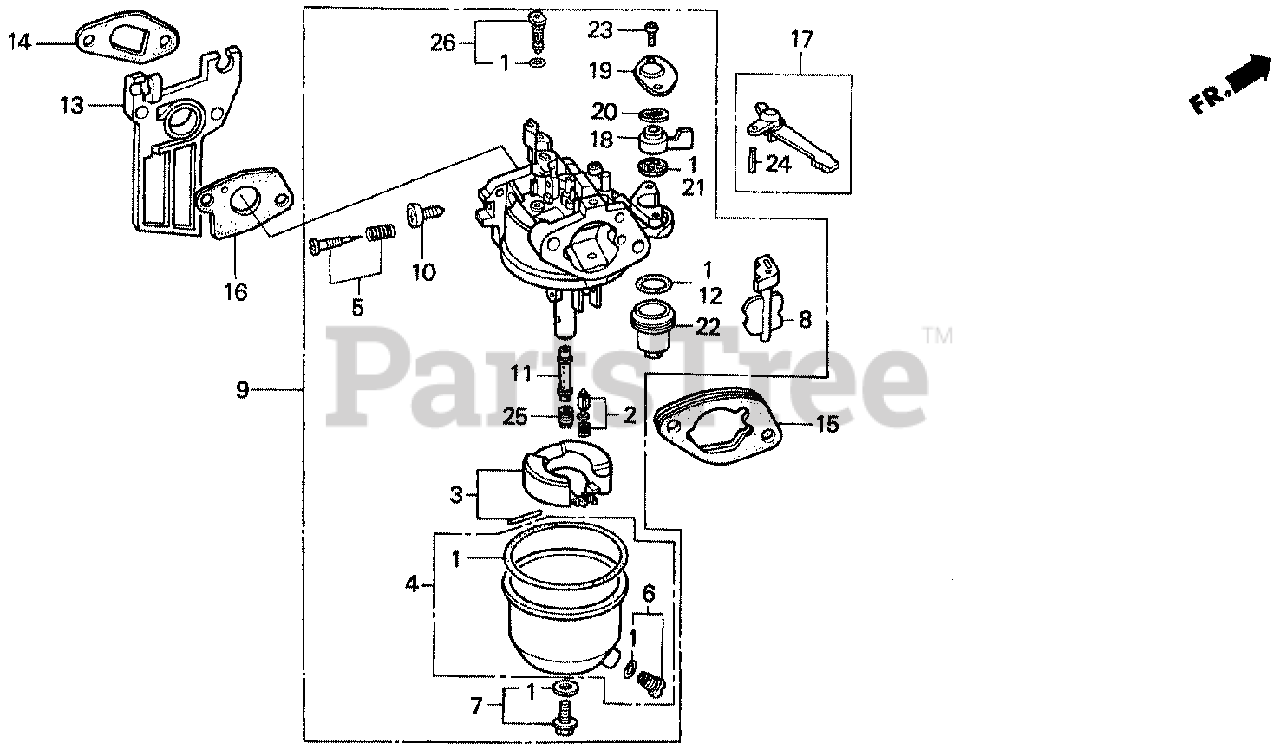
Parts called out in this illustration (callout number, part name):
1	GASKET SET
2	VALVE SET, FLOAT
4	CHAMBER SET, FLOAT
6	SCREW SET, DRAIN
7	SCREW SET B
9	CARBURETOR ASSY. (BE65E B)
10	SCREW, THROTTLE STOP
11	NOZZLE, MAIN
12	GASKET, FUEL STRAINER CUP
13	INSULATOR, CARBURETOR
14	GASKET, INSULATOR
15	SPACER, CARBURETOR
16	GASKET, CARBURETOR
17	LEVER, CHOKE (STD)
18	LEVER, VALVE
19	PLATE, LEVER SETTING
20	SPRING, VALVE LEVER
21	GASKET, VALVE
22	CUP, FUEL STRAINER
23	SCREW, PAN (3X6)
23	SCREW, PAN (3X8)
24	PIN, SPRING (2X12)
25	JET, MAIN (#65)
25	JET, MAIN (#68)
25	JET, MAIN (#70)
26	JET SET, PILOT (#35)
